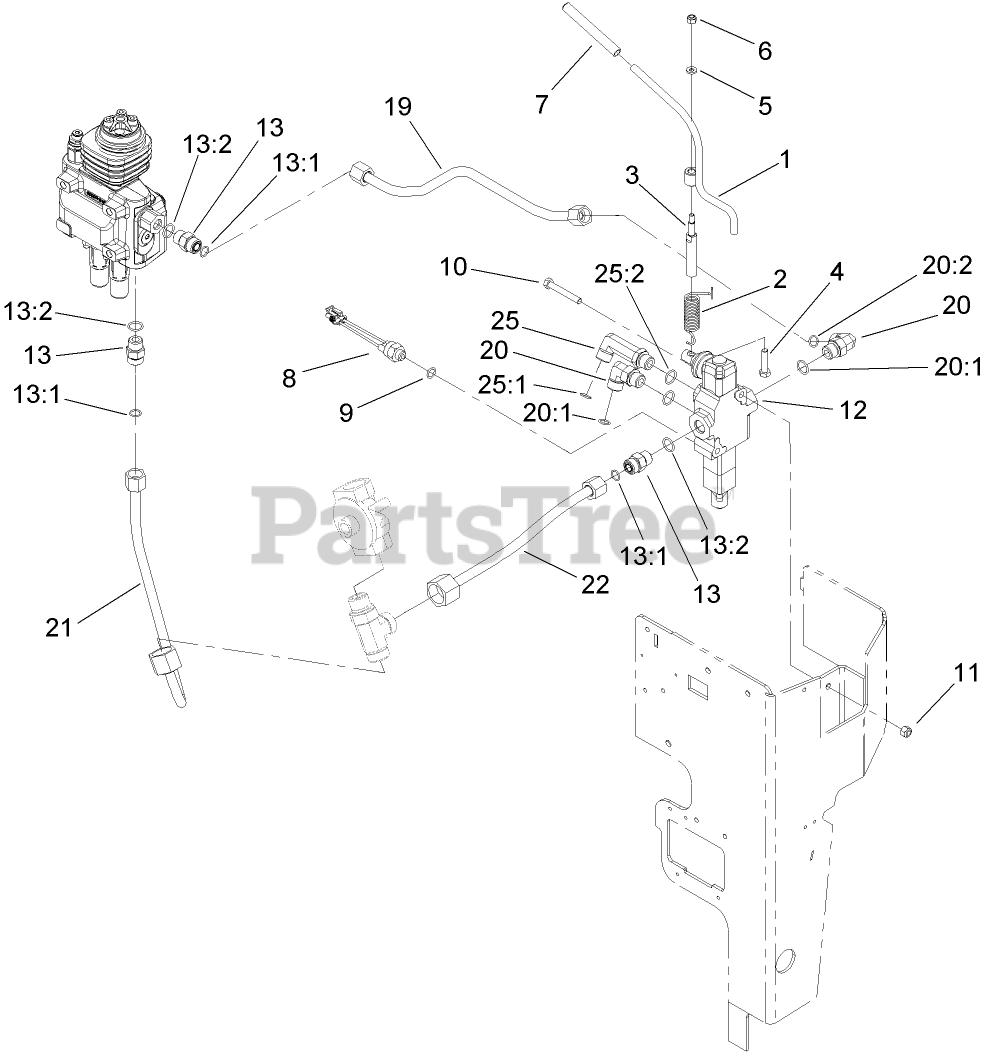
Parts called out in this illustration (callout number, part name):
1	AUXILIARY LEVER ASM
2	SPRING-TORSION
3	SPACER-HIFLO
4	SCREW
5	WASHER-FLAT
6	NUT-LOCK, NI
7	CAP-ROD, TILT
8	SWITCH-BALL
9	O-RING
10	SCREW-HH
11	NUT-LOCK, NI
12	VALVE-1 SPOOL
13	FITTING-STRAIGHT
13:1	O-RING
13:2	O-RING
19	HYD TUBE ASM
20	FITTING-ELBOW-90 DEG
20:1	O-RING
20:2	O-RING
21	HYD TUBE ASM
22	HYD TUBE ASM
25	FITTING-ELBOW, 90 DEG
25:1	O-RING
25:2	O-RING
